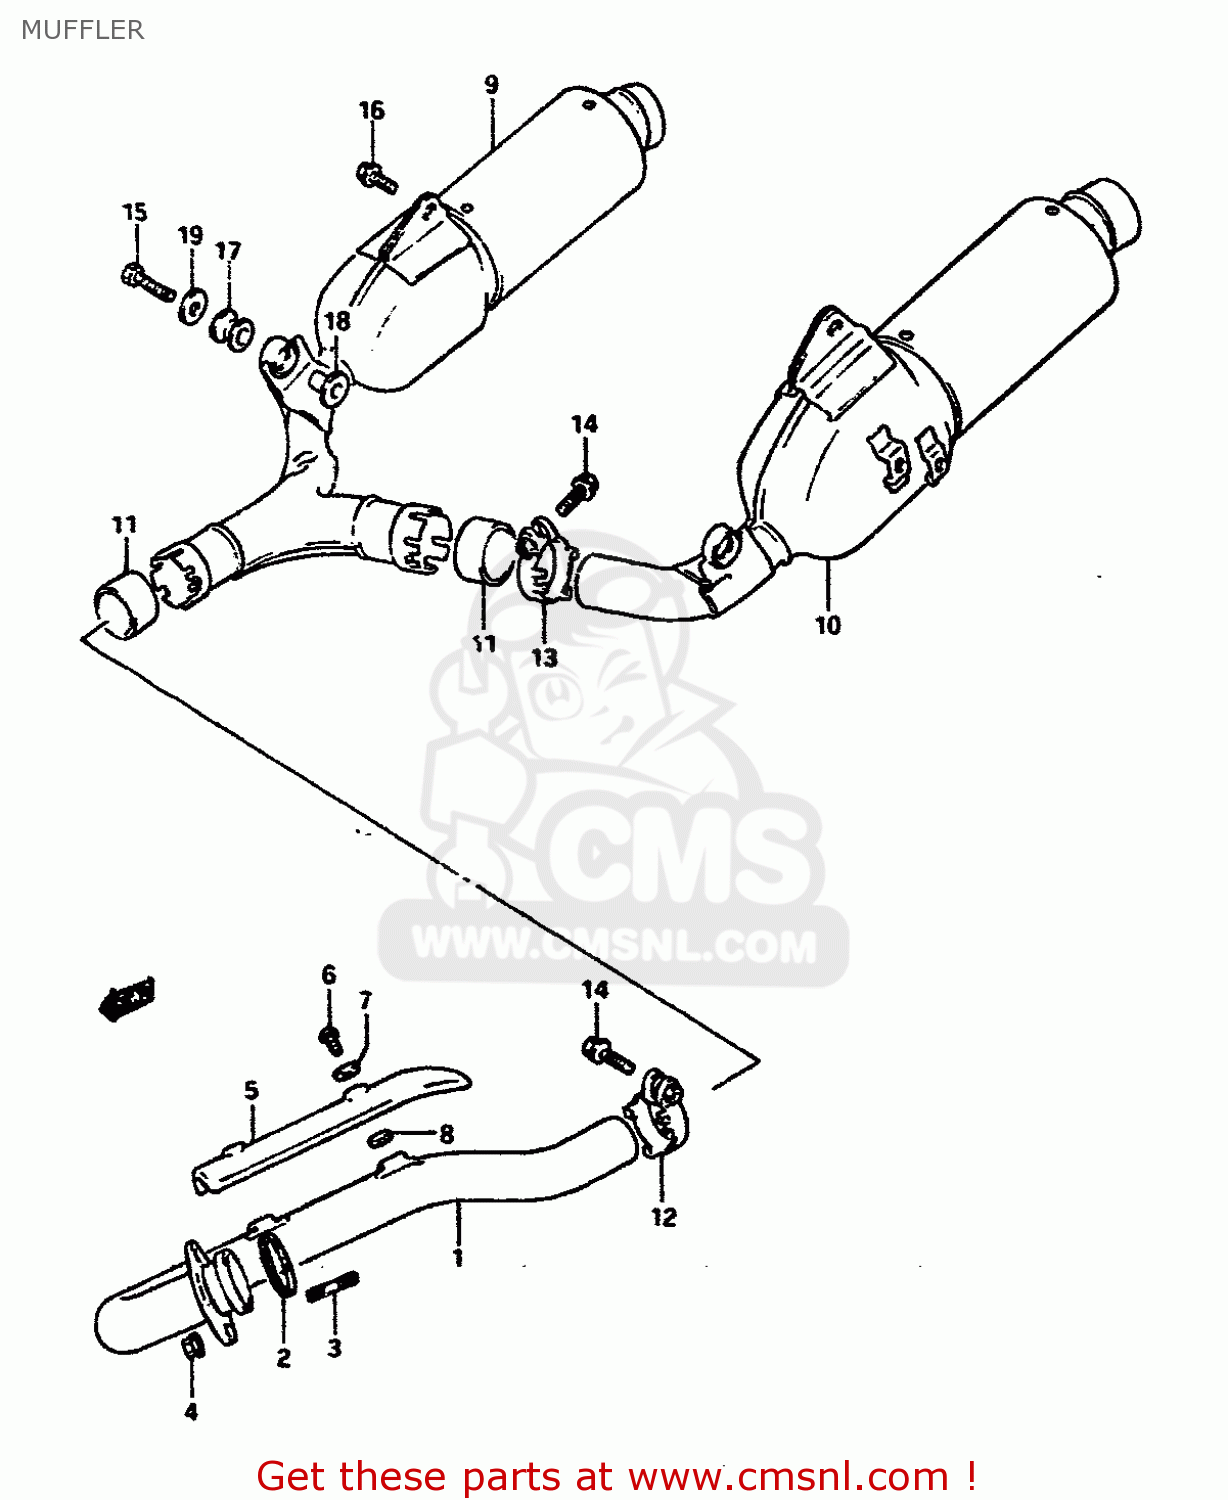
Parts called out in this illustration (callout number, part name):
1	PIPE,EXHAUST
2	GASKET,EXHAUST PIPE (NAS)
3	STUD BOLT
4	NUT
5	COVER,EXHAUST PIPE
6	SCREW(6X10)
7	WASHER(6.5X18X1)
8	GASKET(6X16X1.4) (NAS)
9	MUFFLER ASSY,RH
10	MUFFLER,L
11	CONNECTOR,MUFF
12	CLAMP,MUFFLER CONNECTOR
13	CLAMP,MUFFLER CONNECTOR
14	BOLT
15	BOLT 8X40
16	BOLT(8X20)
17	CUSHION
18	SPACER(8.6X12X17.5)
19	WASHER (8.5X19X2.3)
